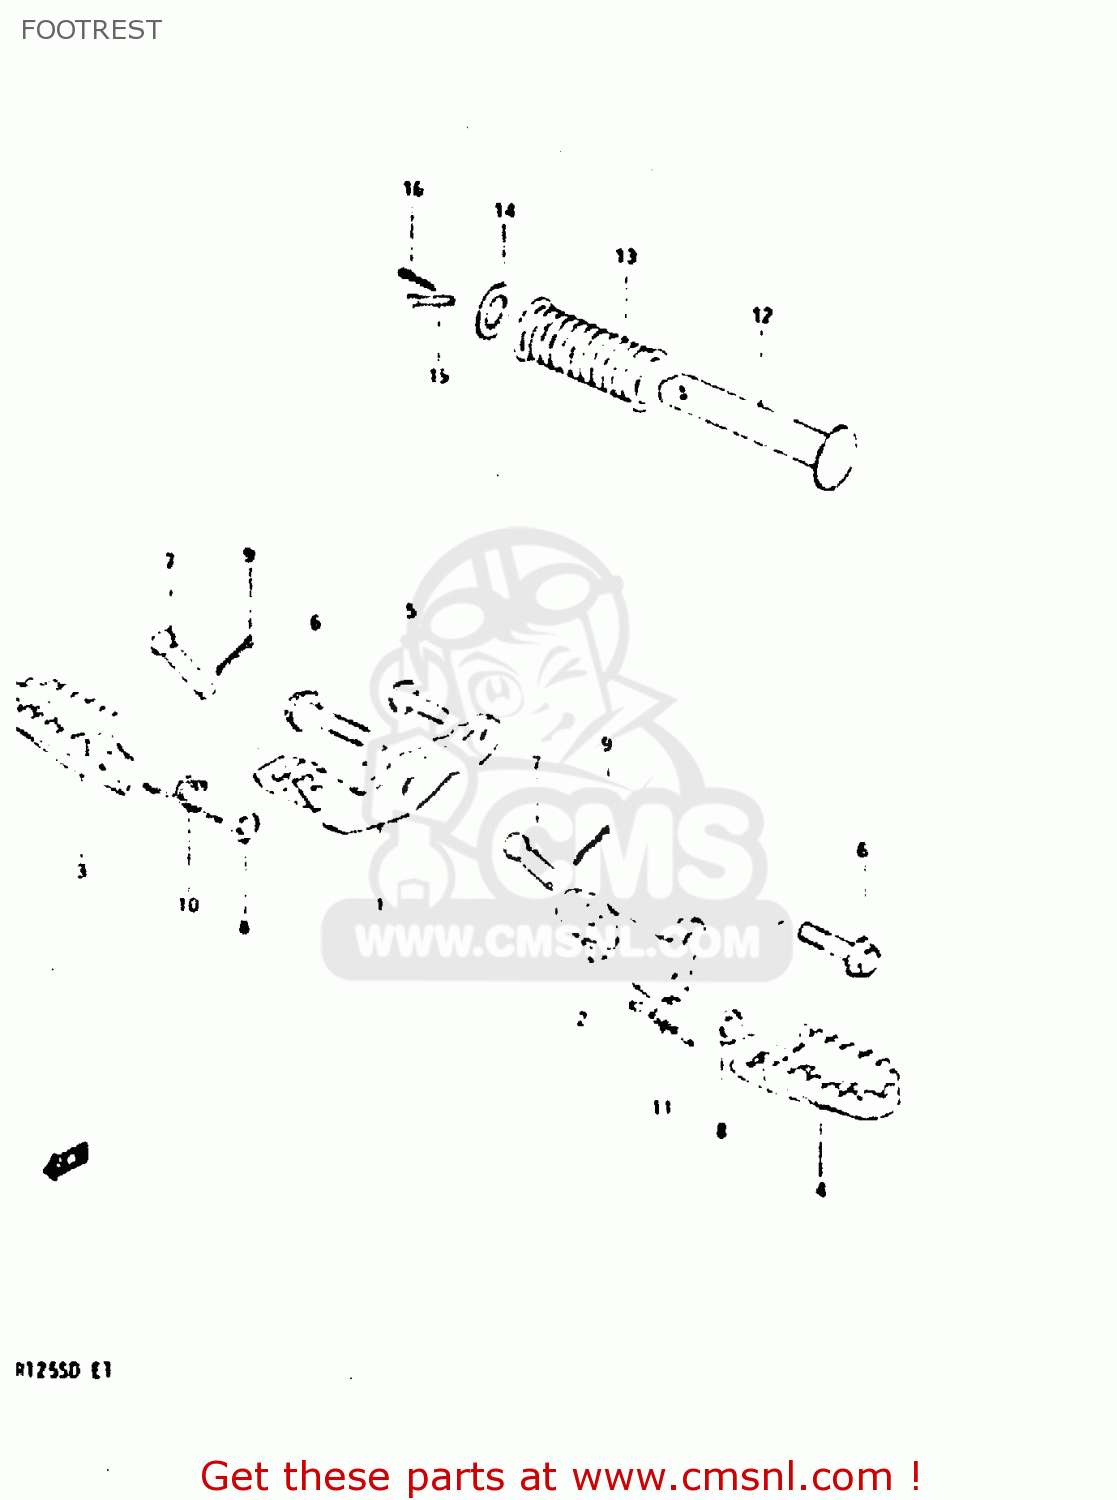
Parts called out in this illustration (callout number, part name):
1	BAR,FRONT FOOTREST
2	BAR,FRONT FOOTREST,LEFT
3	FOOTREST,RIGHT
4	FOOTREST
5	BOLT
6	BOLT
7	PIN
8	WASHER
9	PIN 20X20
10	SPRING
11	SPRING,FOOTREST,LEFT
12	BAR,FOOTREST RUBBER
13	RUBBER,PILLION FOOTREST
14	WASHER (19.5X32X2)
15	PIN
16	PIN 20X20
